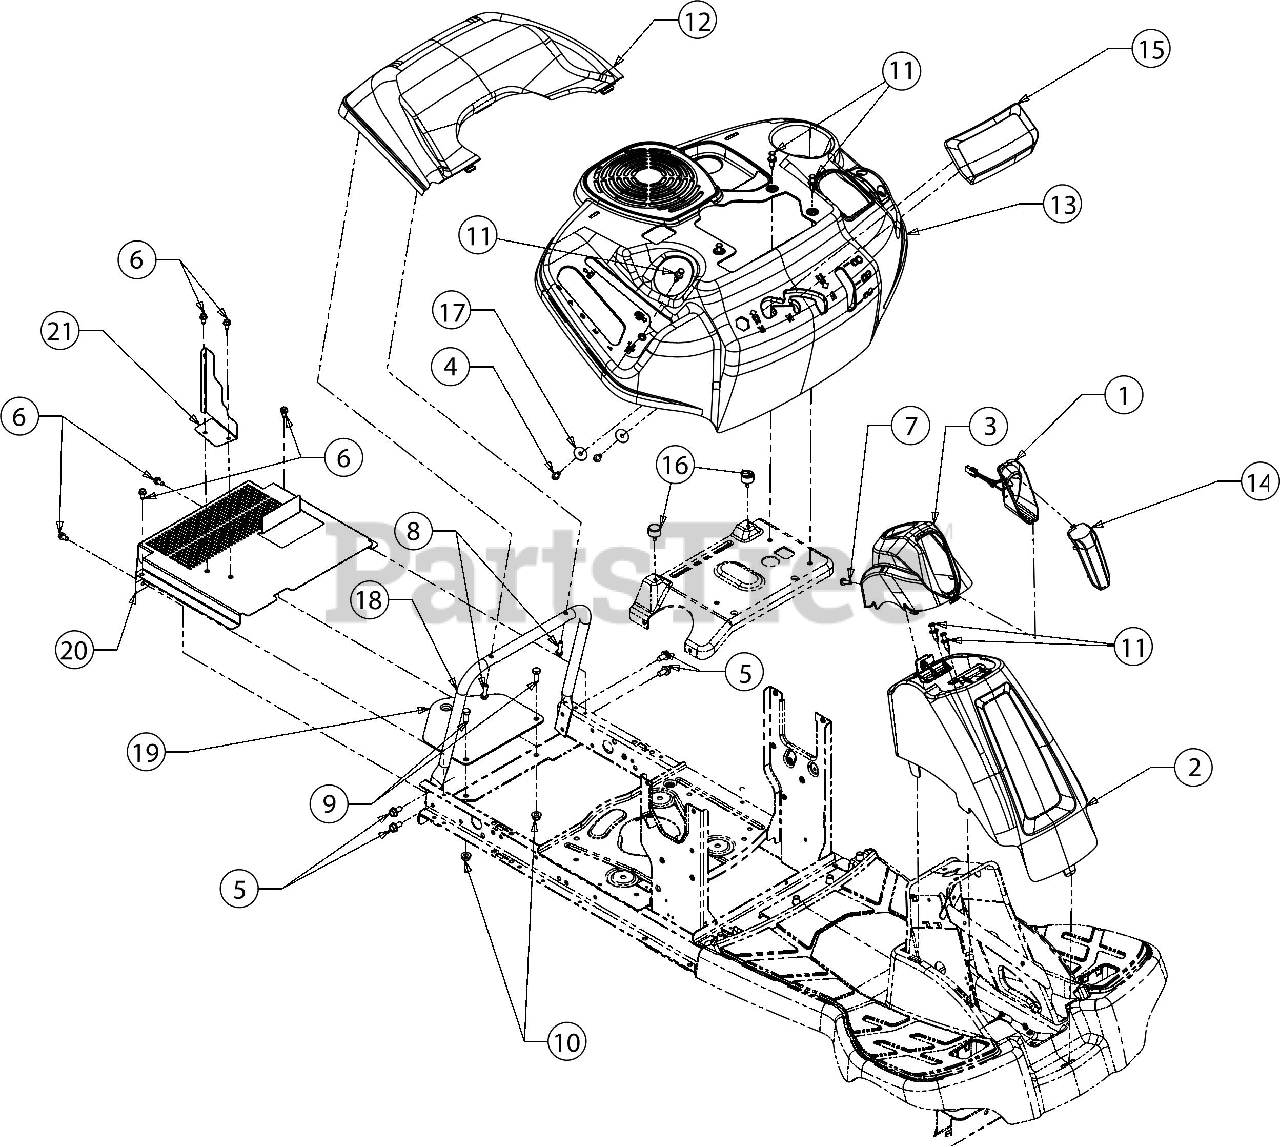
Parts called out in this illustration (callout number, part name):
1	HEADLIGHT HARNESS ASSEMBLY
2	COLUMN COVER ASSEMBLY (CUB)
3	COLUMN CAP (CUB YELLOW)
4	HEX SCREW 1/4-15 x .50
5	SCREW 5/16-18 x .750
6	SCREW 1/4-20 X.500
7	SCREW 1/4-20X.75
8	SCREW 1/4-15 x 1.00
9	SCREW 5/16-18 x .75 GR5
10	FLANGE LOCK NUT 5/16-18
11	PLASTIC RIVET
14	LED HEADLIGHT LENS
15	FENDER COVER
16	BUMPER .62 DIA x .50
17	FLAT WASHER
18	REAR SUPPORT TUBE
19	HITCH PLATE
20	HEAT SHIELD
21	CARBURETOR SHIELD
